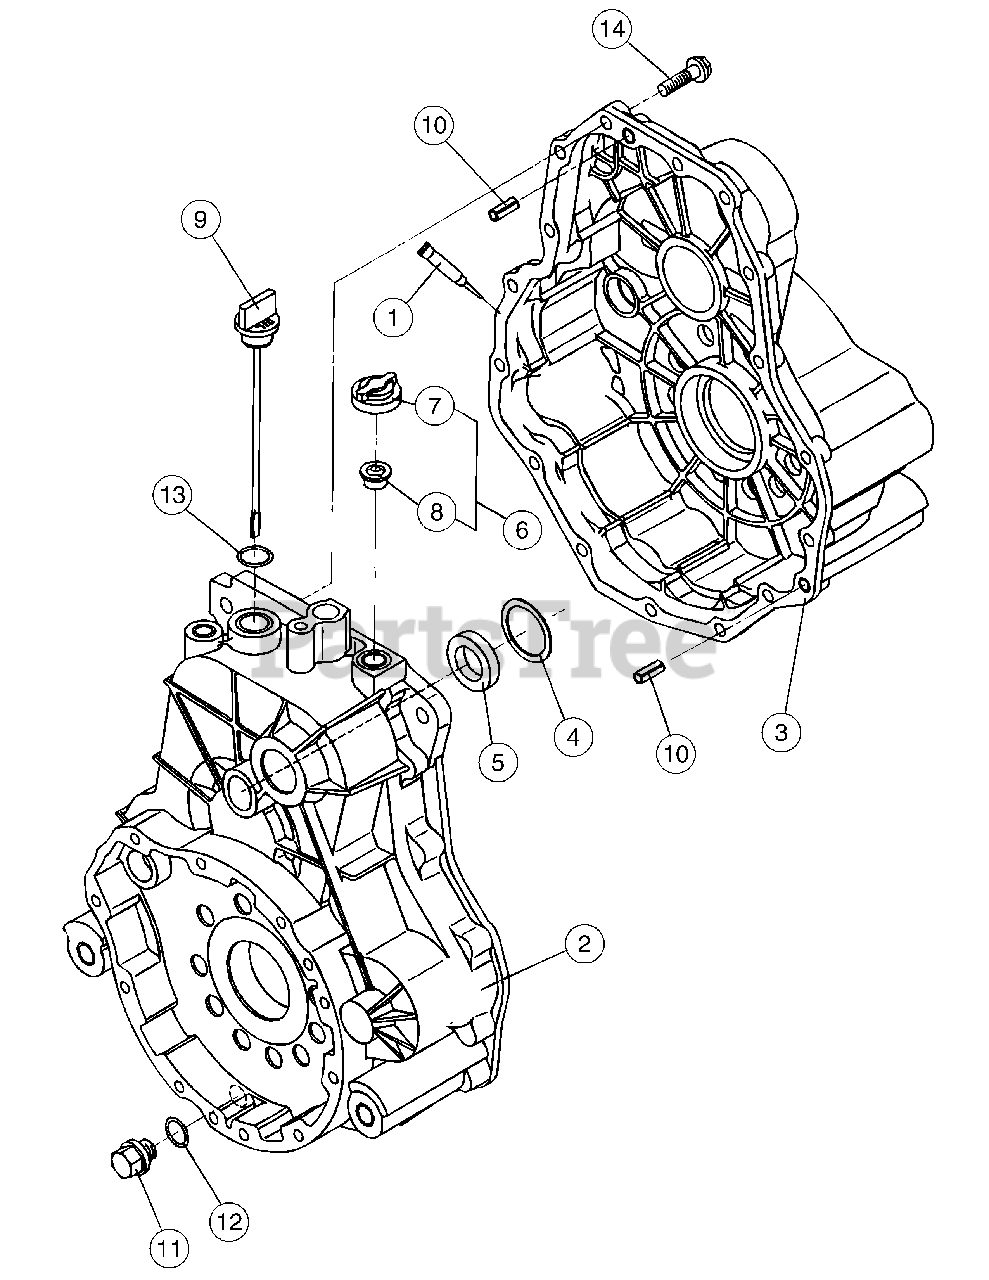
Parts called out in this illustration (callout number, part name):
1	Sealant
2	Housing, Transaxle, Left
3	Housing, Transaxle, Right
4	Washer, 36 x 45.5 x 1.2
5	Seal, TC 30 40 8
6	Vent Valve
7	Cap, Vent Valve
8	Body, Vent Valve
10	Pin, 8 x 20
11	Plug, 14
12	Packing, P 16
13	Packing, P 18
14	Bolt, 28 x 10 x 9
